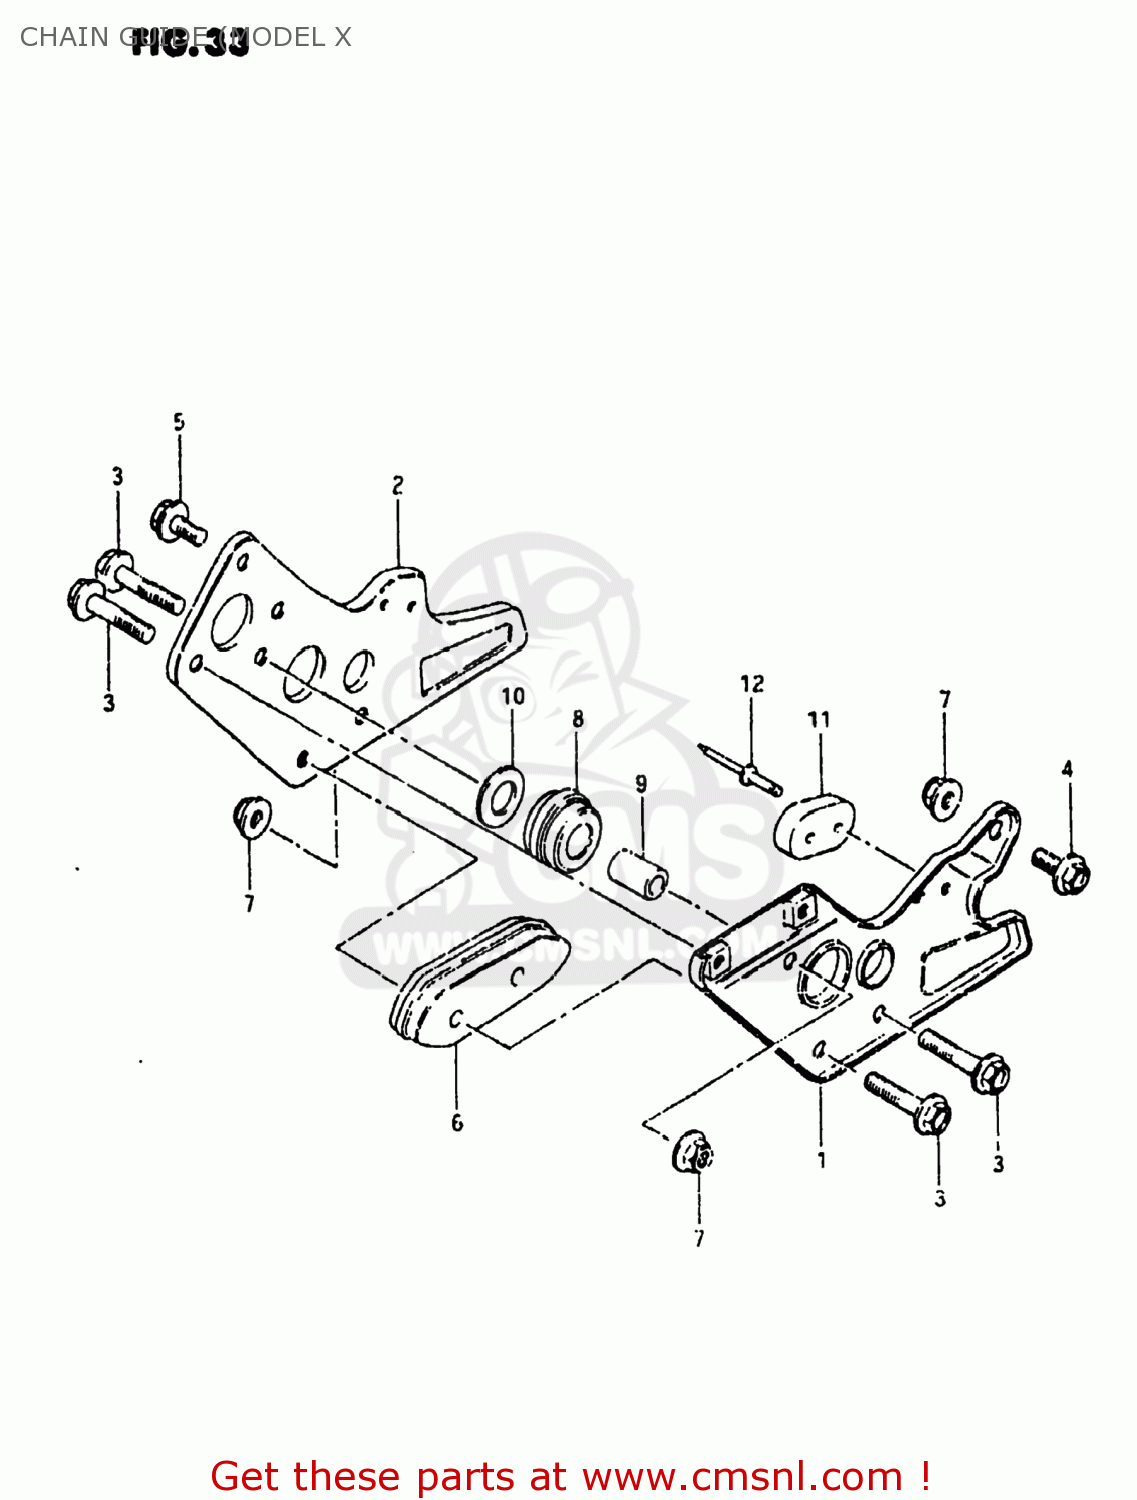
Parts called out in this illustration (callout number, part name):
1	PLATE,CHAIN GUIDE,OUTER
2	PLATE,GUIDE CHAIN
3	BOLT 6X35
4	BOLT
5	BOLT
6	DEFENSE,CHAIN GUIDE
7	NUT
8	ROLLER,CHAIN GUIDE
9	SPACER,CHAIN GUIDE ROLLER
10	WASHER
11	PAD,DRIVE CHAIN GUIDE
12	RIVET
